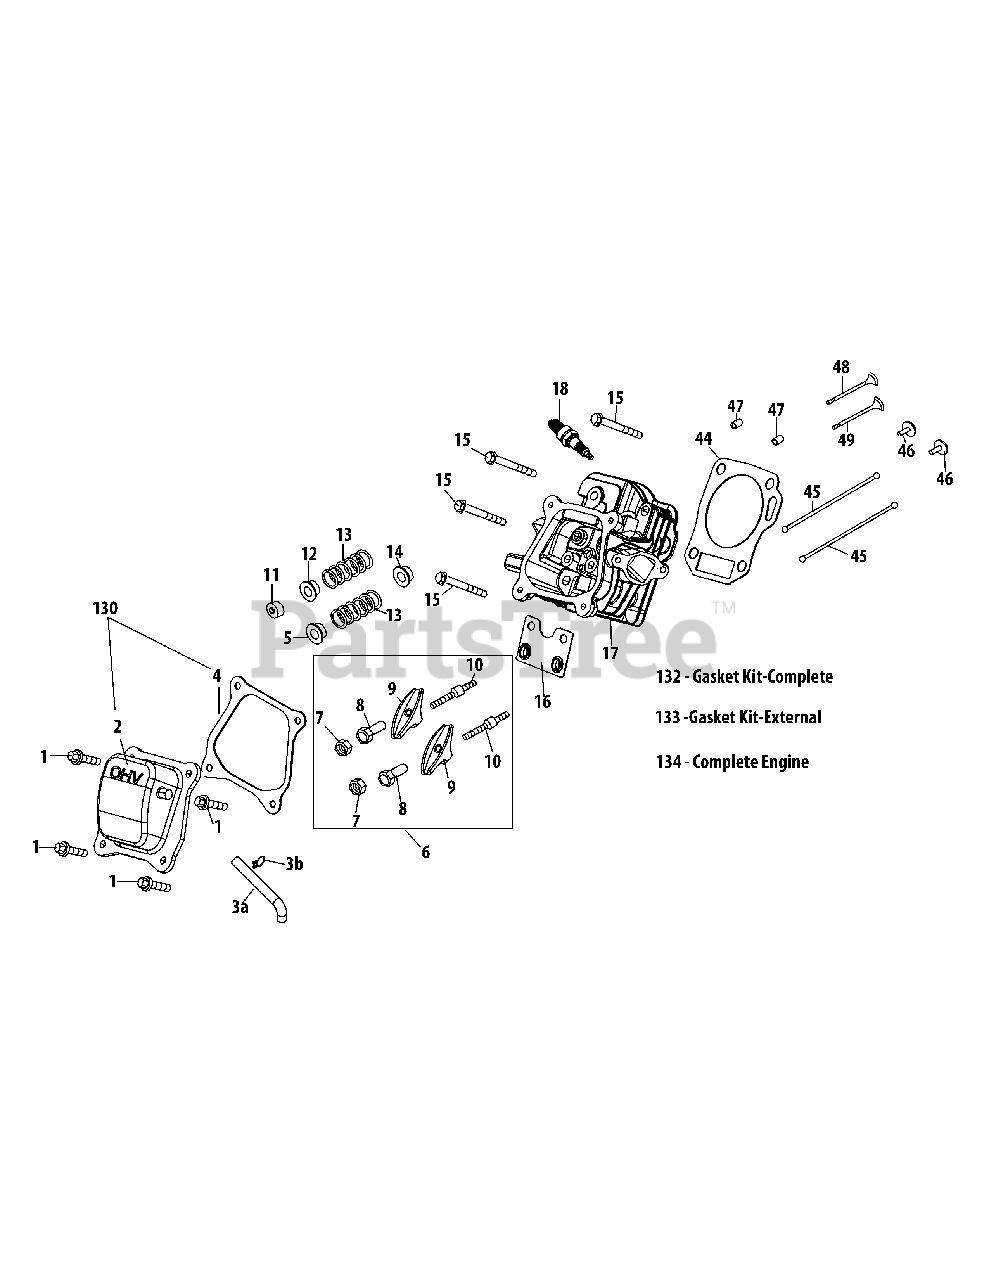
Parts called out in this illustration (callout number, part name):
1	Bolt M6×16
2	Valve Cover
4	Valve Cover Gasket
5	Valve Spring Retainer (Intake)
6	Rocker Arm Assembly
7	Nut, Pivot Locking
8	Adjusting Nut ,Valve
9	Rocker Arm
10	Bolt, Pivot
11	Exhaust Lash Cap
12	Valve Spring Retainer (Exhaust)
13	Valve Spring
14	Valve Seal (Intake)
15	Bolt M8×55
16	Push Rod Guide
17	Cylinder Head Assembly
18	Spark Plug/F6Rtc
44	Gasket, Cylinder Head
45	Push Rod Kit
46	Tappet
47	Dowel Pin 10×16
48	Valve Kit
49	Valve Kit
130	Valve Cover Kit
132	Gasket Kit - Complete
133	Gasket Kit - External
134	Complete Engine
